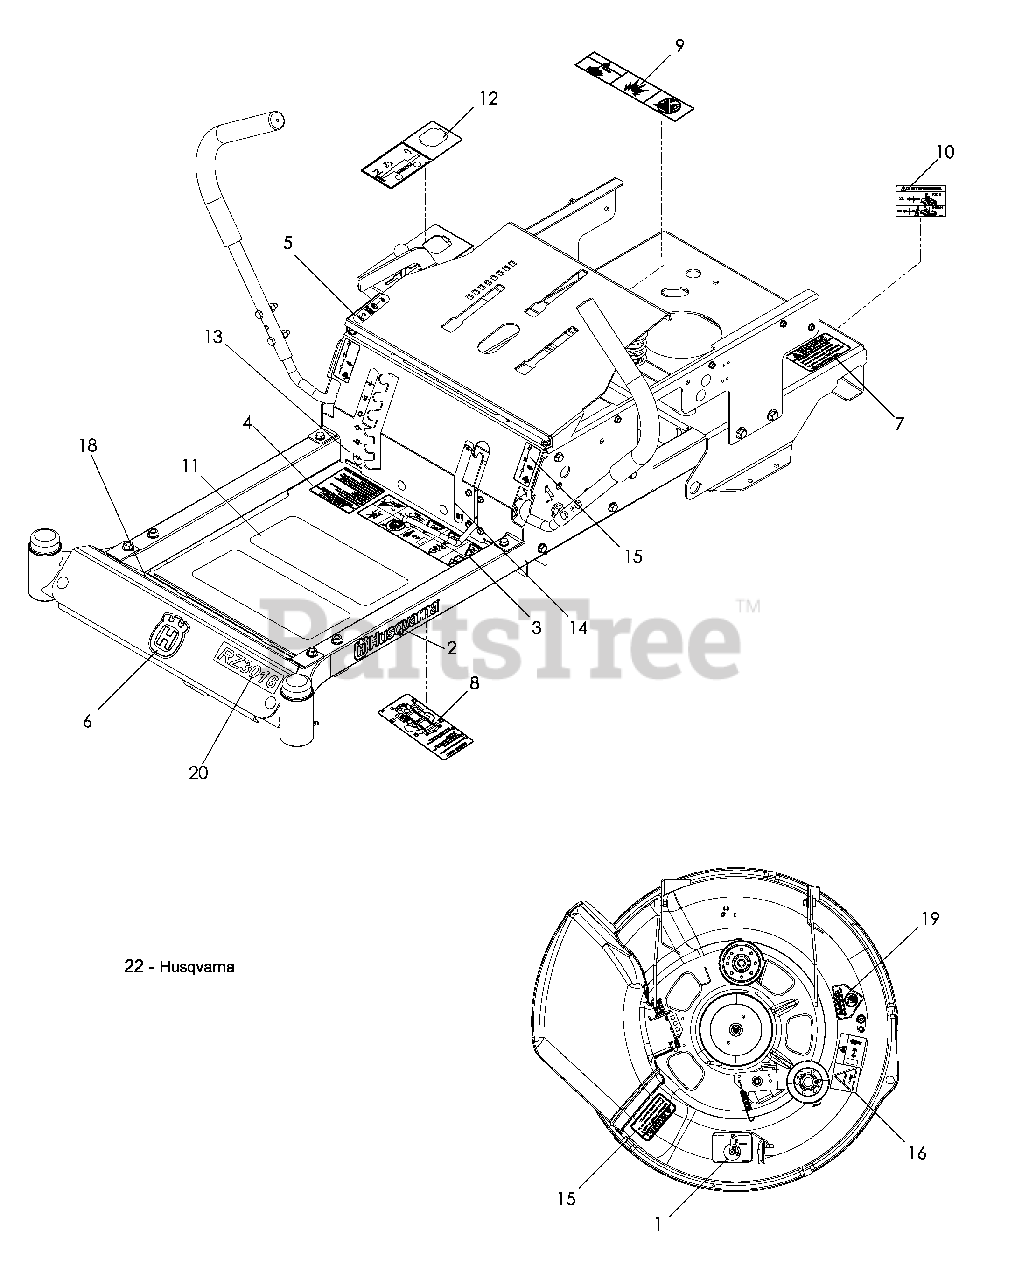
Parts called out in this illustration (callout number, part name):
1	DECAL, BELT ROUTING
2	DECAL, HUSQVARNA
3	DECAL, SAFETY WARNING
4	DECAL, WARNINGS
5	DECAL, PARK BRAKE
6	DECAL, CROWN
7	DECAL, PROP 65
8	DECAL, SERVICE
9	DECAL, BATTERY WARNING
10	DECAL, DO NOT TOW
11	PAD, ABRASIVE
12	DECAL, CONTROL PANEL
13	DECAL, DECK HEIGHT
14	DECAL, BLADE ENGAGE
15	DECAL, MOTION CONTROL
16	DECAL, WARNING
17	DECAL, BLADE WARN
19	DECAL, SEVERING
20	DECAL, RZ3016
